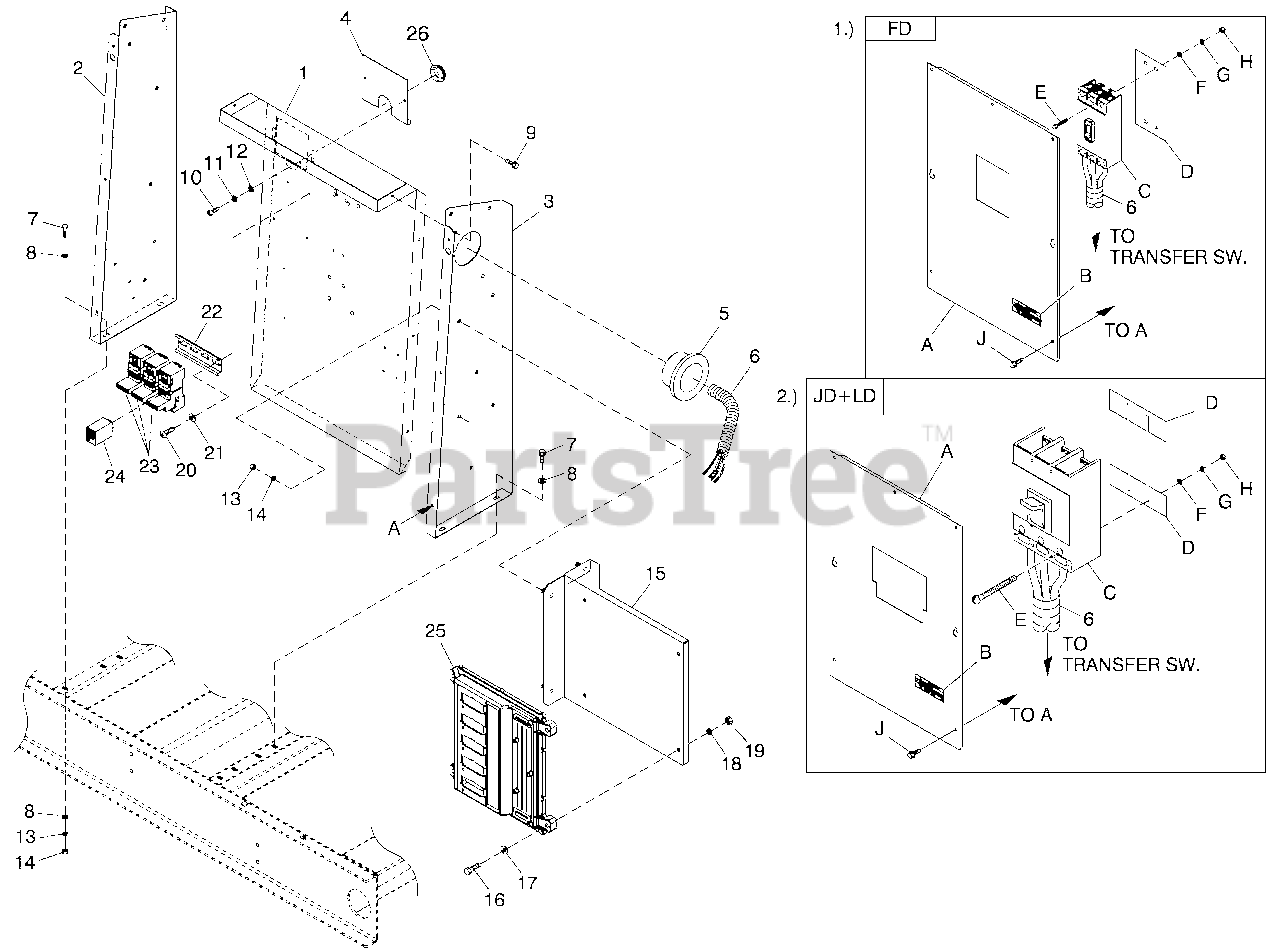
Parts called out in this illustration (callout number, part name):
1	PANEL CB CONN BOX
2	STAND LH CONTROL C5 GRBX
3	STAND RH CONTROL C5
4	PLATE WIRE BLANK
5	BUSHING SNAP SB-2.5-31
6	CONDUIT FLEX 2.0" ID
7	SCREW HHTT M6-1.0 X 16 ZYC
8	WASHER FLAT 1/4-M6 ZINC
9	SCREW THF M6-1 X 16 N WA Z/JS
10	SCREW PHTT M5-0.8 X 16 ZYC
11	WASHER LOCK M5
12	WASHER FLAT M5
13	WASHER LOCK M6-1/4
14	NUT HEX M6 X 1.0 G8 YEL CHR
15	MOUNT POWER MANAGER CPL
16	SCREW HHC M8-1.25 X 30 G8.8
17	WASHER FLAT 5/16-M8 ZINC
18	WASHER LOCK M8 ZINC
19	NUT HEX M8-1.25 G8 CLEAR ZINC
20	SCREW PHTT M4-0.7 X 10 ZYC
21	WASHER LOCK #8-M4
22	RAIL TERMINAL BLOCK 98MM
23	BASE RELAY DIN MOUNT 4PDT 14P
24	RELAY 4PDT 12VDC COIL 5A 250V
25	ASSY PROGRAMMED PMGC
26	GROMMET 1.25 X .25 X .75
A	DECAL DANGER HIGH VOLTAGE
B	CB 0150A 3P 600V S FD6 2A
C	CB 0175A 3P 600V S FD6 1A
D	INSULATOR CB FD FRAME 30MIL
E	SCREW SHC 1/4-20 X 4 G8.8 NZ
F	WASHER FLAT 1/4-M6 ZINC
G	WASHER LOCK M6-1/4
H	NUT HEX 1/4-20 STEEL
J	SCREW THF M6-1 X 16 N WA Z/JS
A	COVER CIR BRKR JD/LD
B	DECAL DANGER HIGH VOLTAGE
C	CB 0300A 3P 600V S JD6 LL
D	INSULATOR CIRCUIT BR. JD/LD
E	SCREW RHM 1/4-20 X 3
